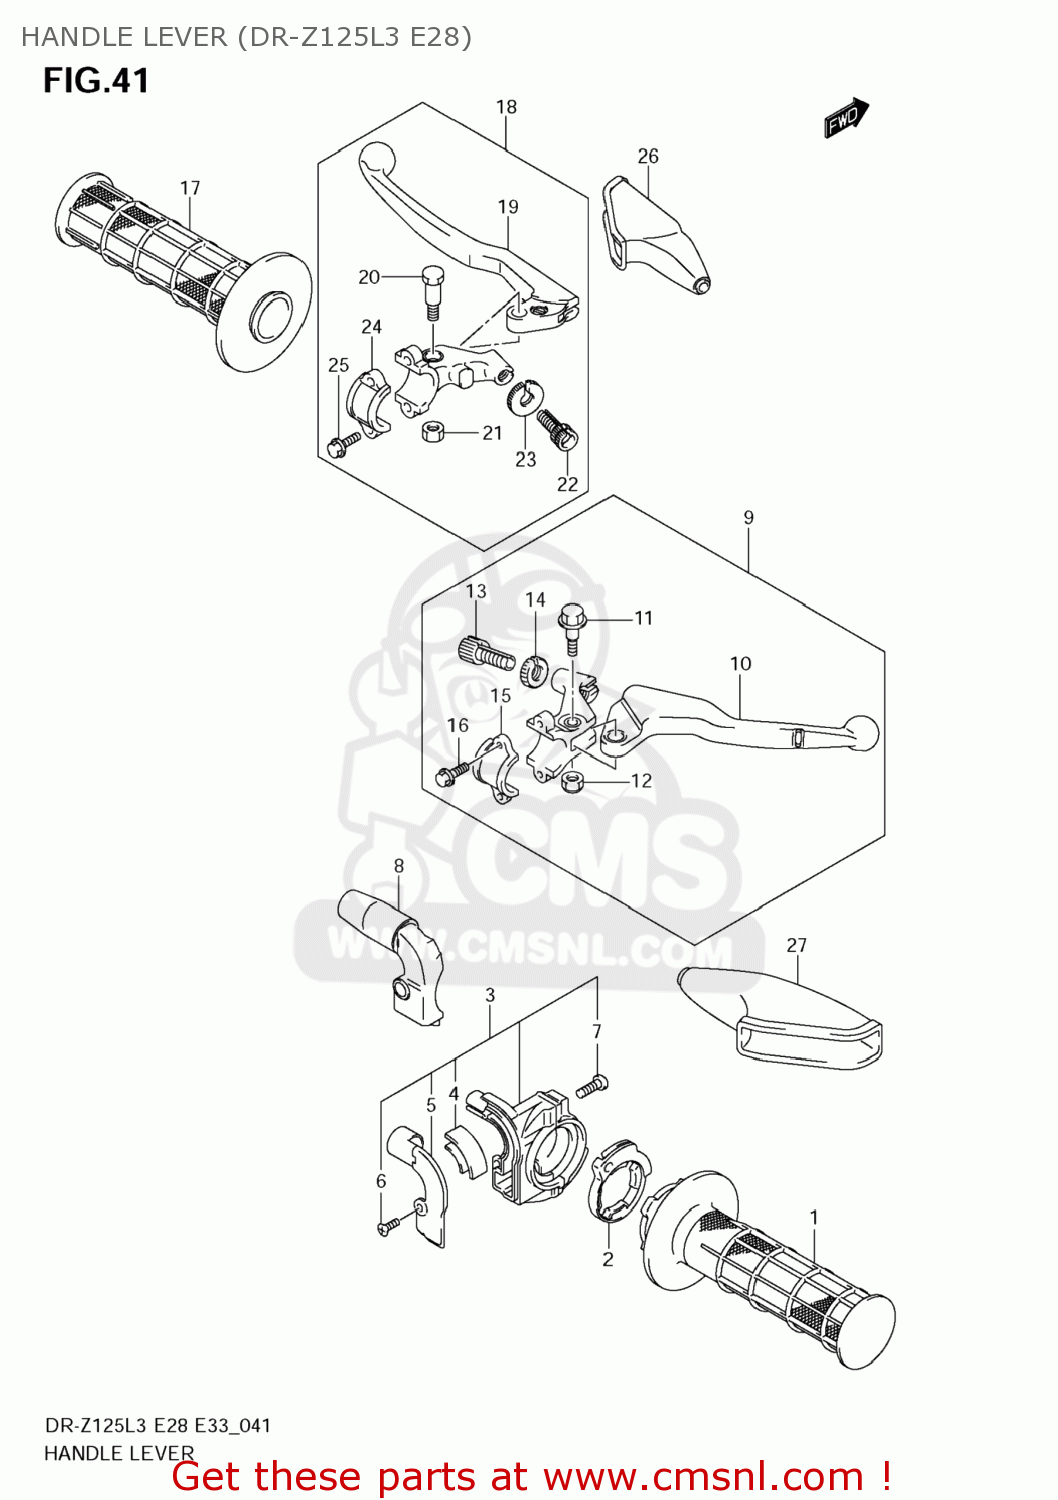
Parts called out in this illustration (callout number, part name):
1	GRIP,THROTTLE
2	ROTER,THROTTLE
3	CASE ASSY,THROTTLE
4	GUIDE
5	COVER
6	SCREW
7	SCREW
8	COVER,THROTTLE CASE
9	LEVER ASSY,BRAKE
10	LEVER,BRAKE
11	BOLT,LEVER PIVOT
12	NUT
13	ADJUSTER,WIRE
14	NUT,LOCK
15	HOLDER
16	BOLT
17	GRIP,L
18	LEVER ASSY,CLUTCH
19	LEVER,CLUTCH
20	BOLT,LEVER PIVOT
21	NUT
22	ADJUSTER,WIRE
23	NUT,LOCK
24	BRACKET,CLUTCH LEVER HOLDER
25	BOLT,BRACKET
26	COVER,CLUTCH CABLE DUST
27	COVER,CLUTCH LEVER
